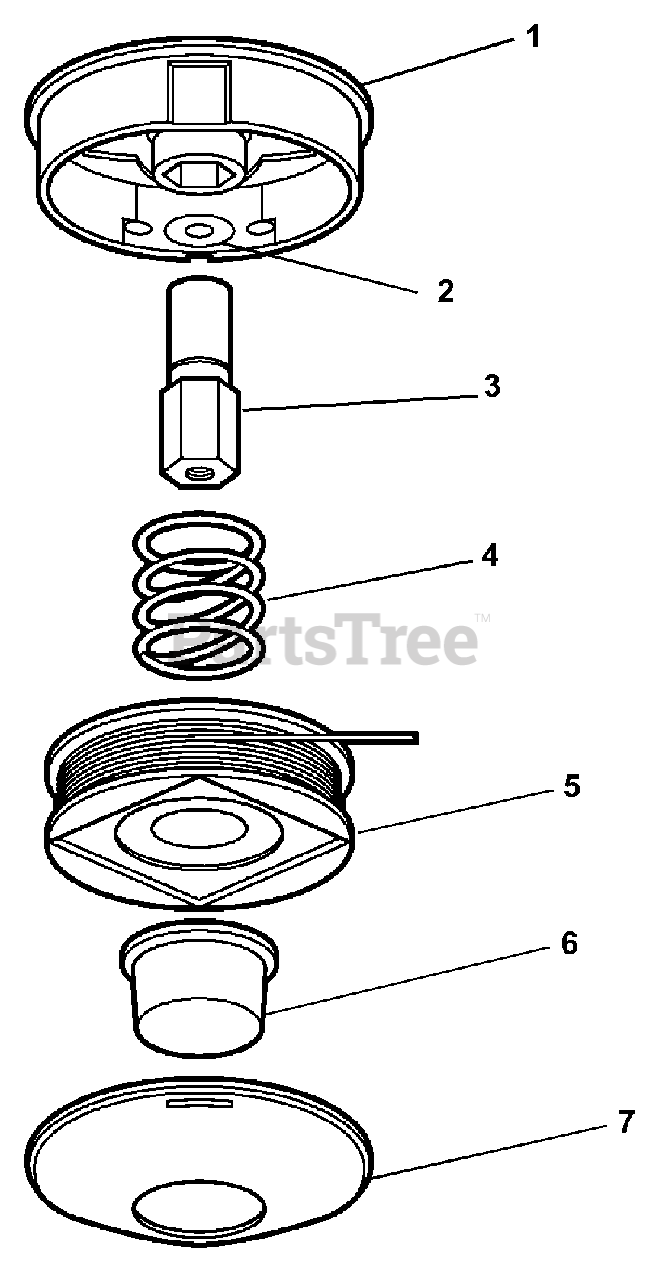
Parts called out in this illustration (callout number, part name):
1	HOUSING
2	EYELET
4	SPRING
5	REEL, ROPE
6	BUTTON
7	COVER
